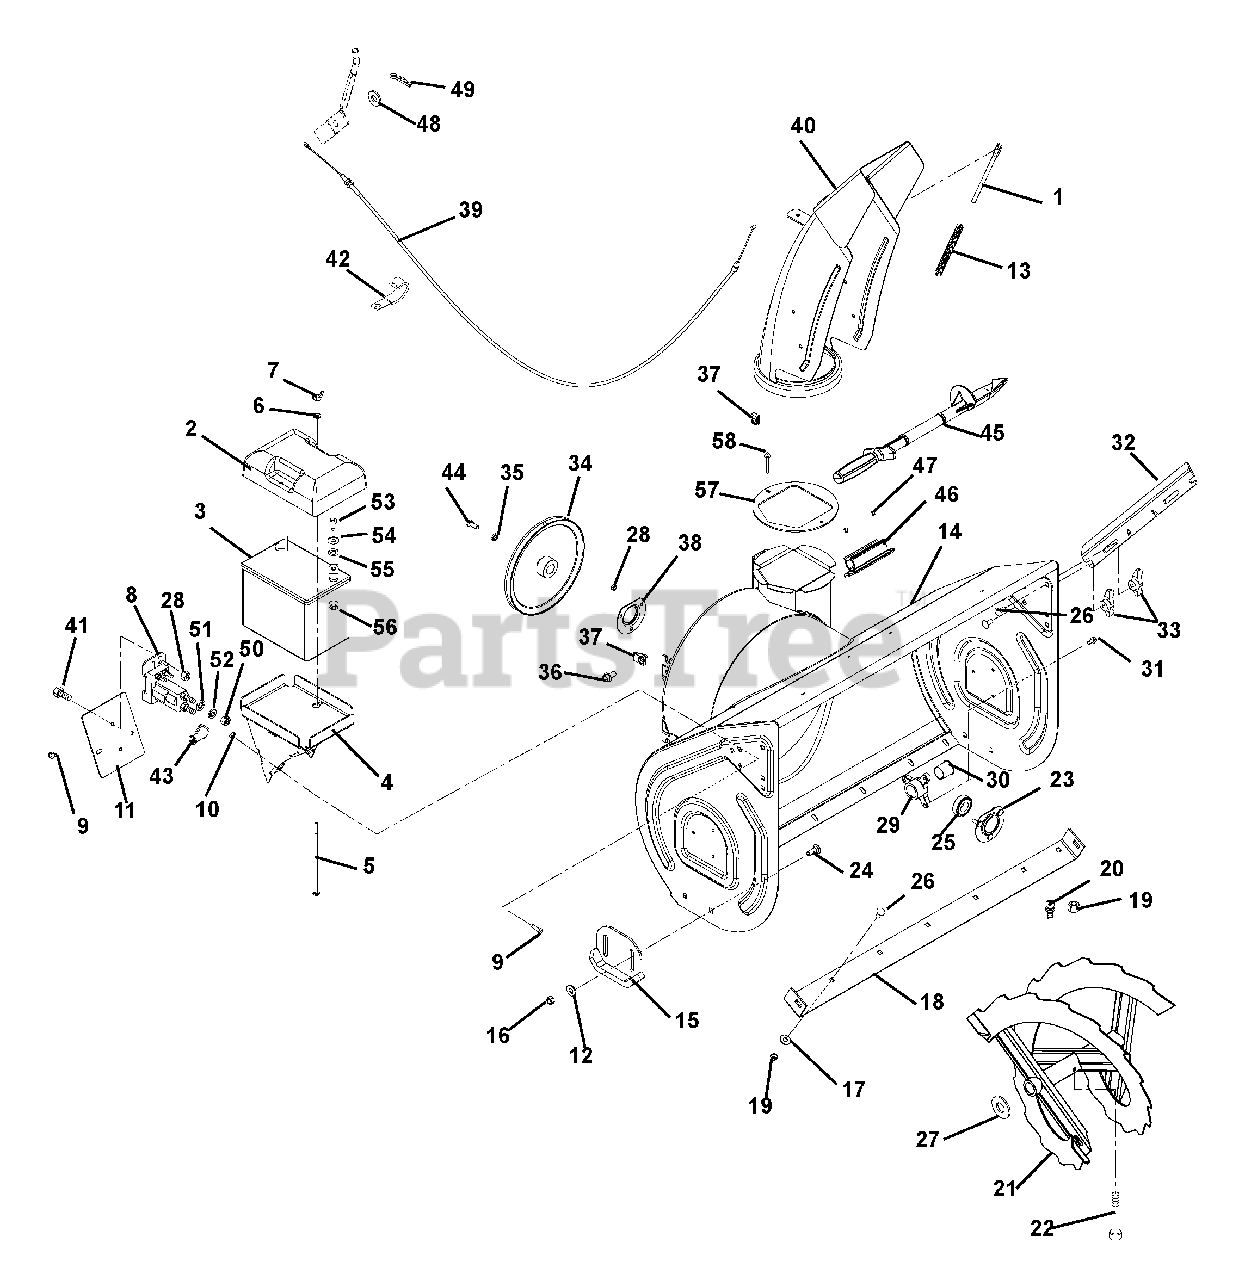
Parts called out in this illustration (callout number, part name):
1	ROD, DEFLECTOR CAP
2	COVER, BATTERY
4	TRAY, BATTERY-W/CLIPS
5	@BLT-RDHDSQNK .25-20X7.00 G2YZ
6	@WSHR-FL-STL.281X.62X.065 YWZC
7	NUT-LK WING .250-20 YWZC
8	SOLENOID
9	@SCR-MCH .25-20X.75 HWH YWZC
10	NUT-RTNR .25-20X.56
11	COVER, SOLENOID
12	@WSHR-FL-STL.438X1.00X.083 YWZ
13	SG-COMP .08X.40X6.50 14#/IN
14	HOUSING, BLOWER-26" W/DECAL
14	HOUSING, BLOWR-28" W/DECAL
14	HOUSING, BLOWER-32" W/DECAL
14	HOUSING, BLOWER-32"BAT W/DECAL
14	HOUSING, BLOWER-36" W/DECAL
15	RUNNER, SKID SHOE-1/2" FLANGE
15	SKID SHOE, REVERSIBLE - ORANGE
16	@NUT-LK-CTR .38-16 YWZC
17	@WSHR-FL-STL.438X1.00X.083 YWZ
17	@WSHR-FL-STL.38X.875X.083 YWZC
18	BLADE, SCRAPER-26"
18	BLADE, SCRAPER-28"
18	BLADE, SCRAPER-32"
18	BLADE, SCRAPER-36"
19	@NUT-LK-CTR .31-18 YWZC
20	FTG-LUBE .25-28X.256 YWZC
21	RAKE, LH-26"(1 ID X 15.75 OD)
21	RAKE, RH-26" (1 ID X 15.75 OD)
21	RAKE, LH-28" (1 ID X 15.75 OD)
21	RAKE, RH-28" (1 ID X 15.75 OD)
21	RAKE, LH-32" (1 ID X 15.75 OD)
21	RAKE, RH-32" (1 ID X 15.75 OD)
21	RAKE, LH-36" (1ID X 15.75 OD)
21	RAKE, RH-36" (1 ID X 15.75 OD)
22	SHEAR BOLT SERVICE ASSEMBLY
23	BEARING FLANGE
24	@BLT-RDHDSHSQNK.38-16X1.0 G5YZ
25	BRG-BALL .876 X 1.750 X .50
26	@BLT-RHDSSQNK .31-18X.75 G5YZ
27	WSHR-FL-STL 1.010X1.505X.062YZ
28	@NUT-LK-CTR .25-20 YWZC
29	BUSHING, RAKE SHAFT 1"
30	BSHG-FLG, SPLIT NYLINER 1.0"ID
31	@SCR-TAP .25-20X.50 HWH TR YWZ
32	CUTTER, DRIFT
33	KNOB - WING .312-18 UNC
34	PULLEY, 4L W/HUB, .87 X 8.5
35	WSHR-LK .312X.097 HVY YWZC
36	BLT-SERHFWH .38-16X.75 YWZC
37	NUT-RTNR .375-16X.37
38	BEARING FLANGE
39	CABLE, DEFLECTOR
40	CHUTE, DISCHARGE-W/DEFLECTOR
41	@BLT-HEX .25-20X.50 GR5 YWZC
42	J-CLAMP
43	BOOT, EYELET TERMINAL
44	BLT-HEX .31-24X.75 YWZC GR5
45	DEVICE, SNOW CLEAN OUT
46	MOUNT, SNOW CLEAN OUT
47	RVT-POP .187X.45 DOME ALUM
48	@WSHR-FL-STL.281X.62X.065 YWZC
49	PIN-HAIR INT .06X.18X.77
50	NUT-JAM .31-24 YWZC
51	WSHR-LOCK INT .31 YWZC
52	@WSHR-LK .31X.078 REG YWZC
53	@BLT-HEX .25-20X.75 GR5 YWZC
54	WSHR-FL-STL .265X.50X.087YWZC
55	@WSHR-LK .25X.062 REG YWZC
56	@NUT-HEX .25-20 YWZC
57	BAFFLE, DISCHARGE NECK
58	RVT-POP .187X.45 DOME ALUM
